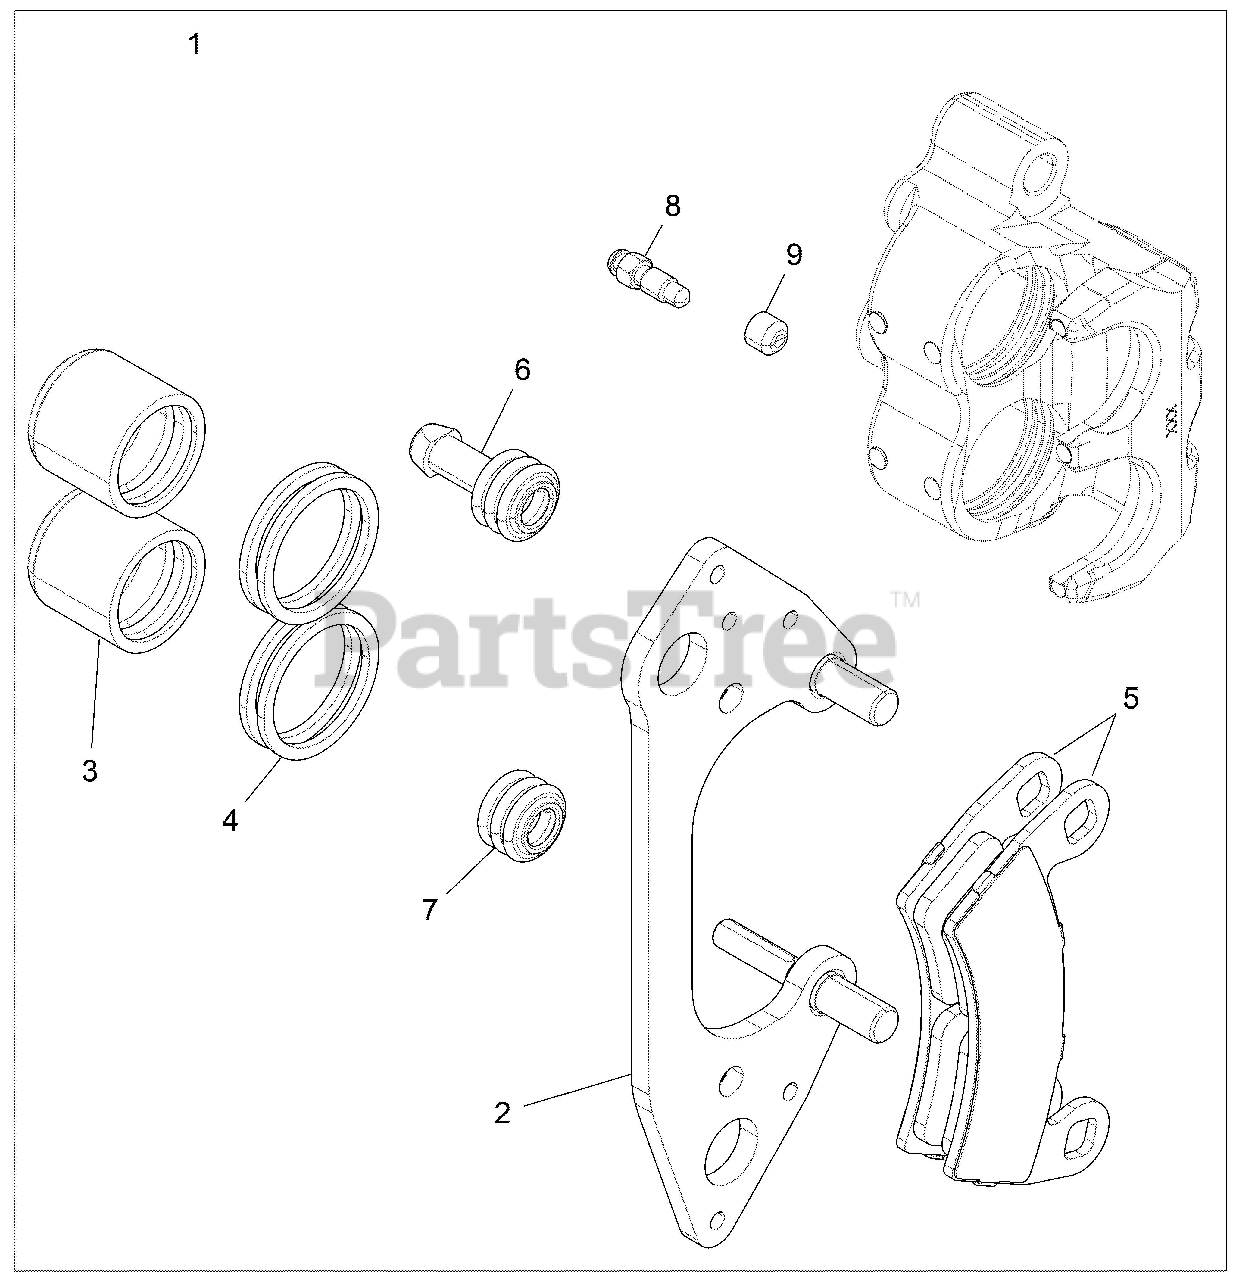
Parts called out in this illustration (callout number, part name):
1	ASM-BRK-CAL-L-DB1-3/8-GROOVED
1	ASM-BRK-CAL-R-DB1-3/8-GROOVED
2	ASM., CALIPER, MOUNT, FRONT
3	PISTON-BRAKE,1.375,AL,GROOVED
4	SEAL-CALIPER,INNER,1.375"
5	KIT-ASM,PAD,BRAKE,DB,1.375
6	BOOT-PIN BUSHING
7	BOOT-PIN SEAL
8	SCR-M7X1.0,BLEEDER,OLIVE D
9	SCR-M10X1.0X8,SOC SET-OD
